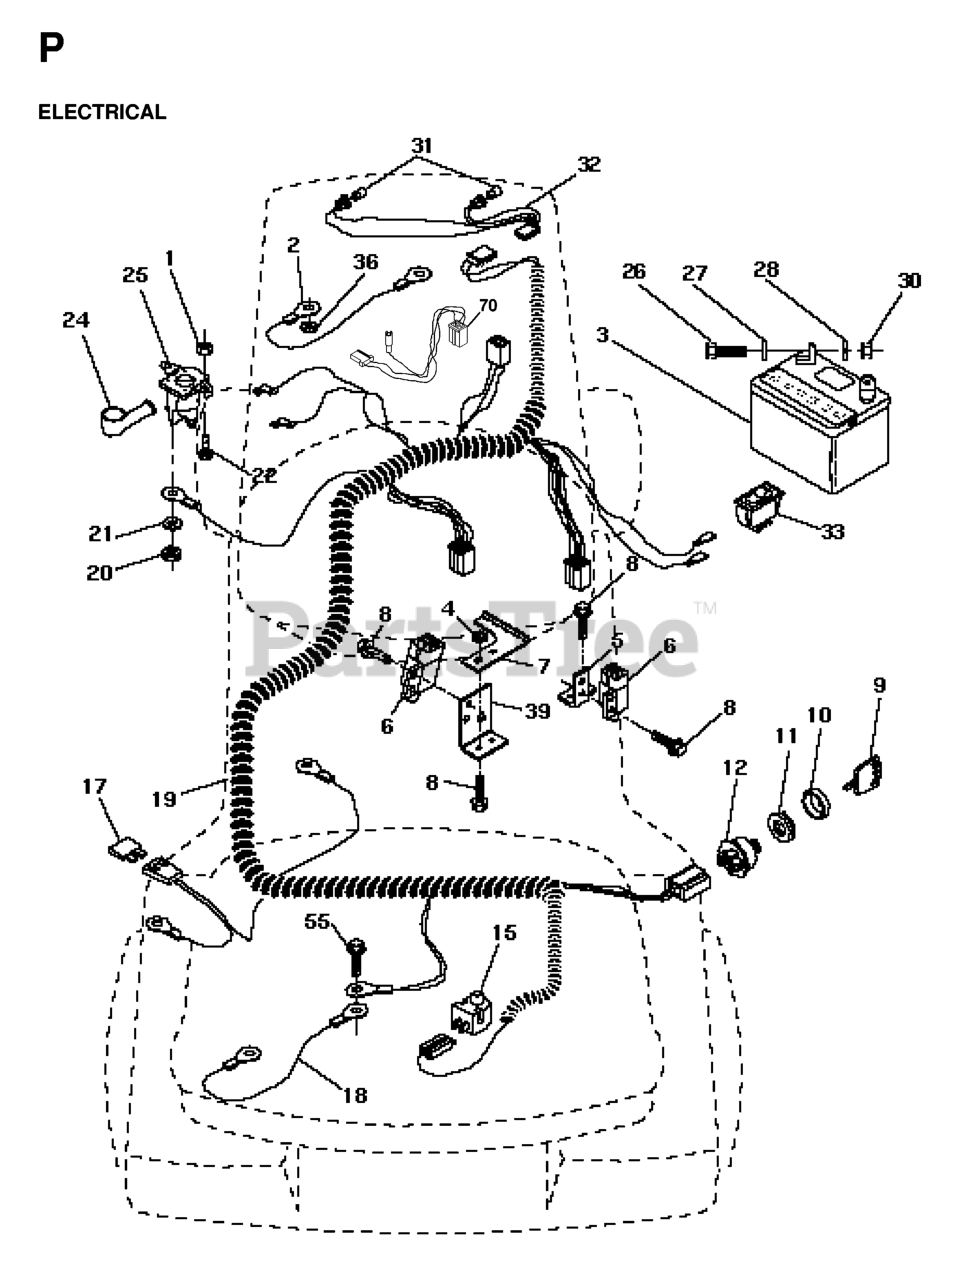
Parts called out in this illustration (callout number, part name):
1	Nut, Keps Blk Hex 1/4-20 UNC
2	CABLE.BATTERY.6GA.16"RED
3	REPL BY 532 12 38-99
5	BRACKET LT
6	SWITCH INTERLOCKT
7	KEEPER, ACTUAT. L.R.
9	KEY MLD GEN DELTA
10	COVER SWITCH KEY
11	NUT, IGNITION
12	IGNITION SWITCH
15	RP.SWITCH.PLUNGER.NC.GRAY
18	CABLE ASSY
19	HARNESS IGN LR NLA
20	NUT
21	LOCKWASHER
22	BOLT
24	TERMINAL COVER
25	REPL BY 532 10 99-46
26	BOLT.HEX.1/4.X.3/4.DICHROMATE
28	LOCKWASHER
30	NUT
32	HARNESS HEADLIGHT
36	Washer, Lock, Internal Tooth 1/4
55	Screw 5/16-18 x 1/2 Hex, Self Tapping 5/16-18 x 1/2
70	HARNESS, ENGINE
